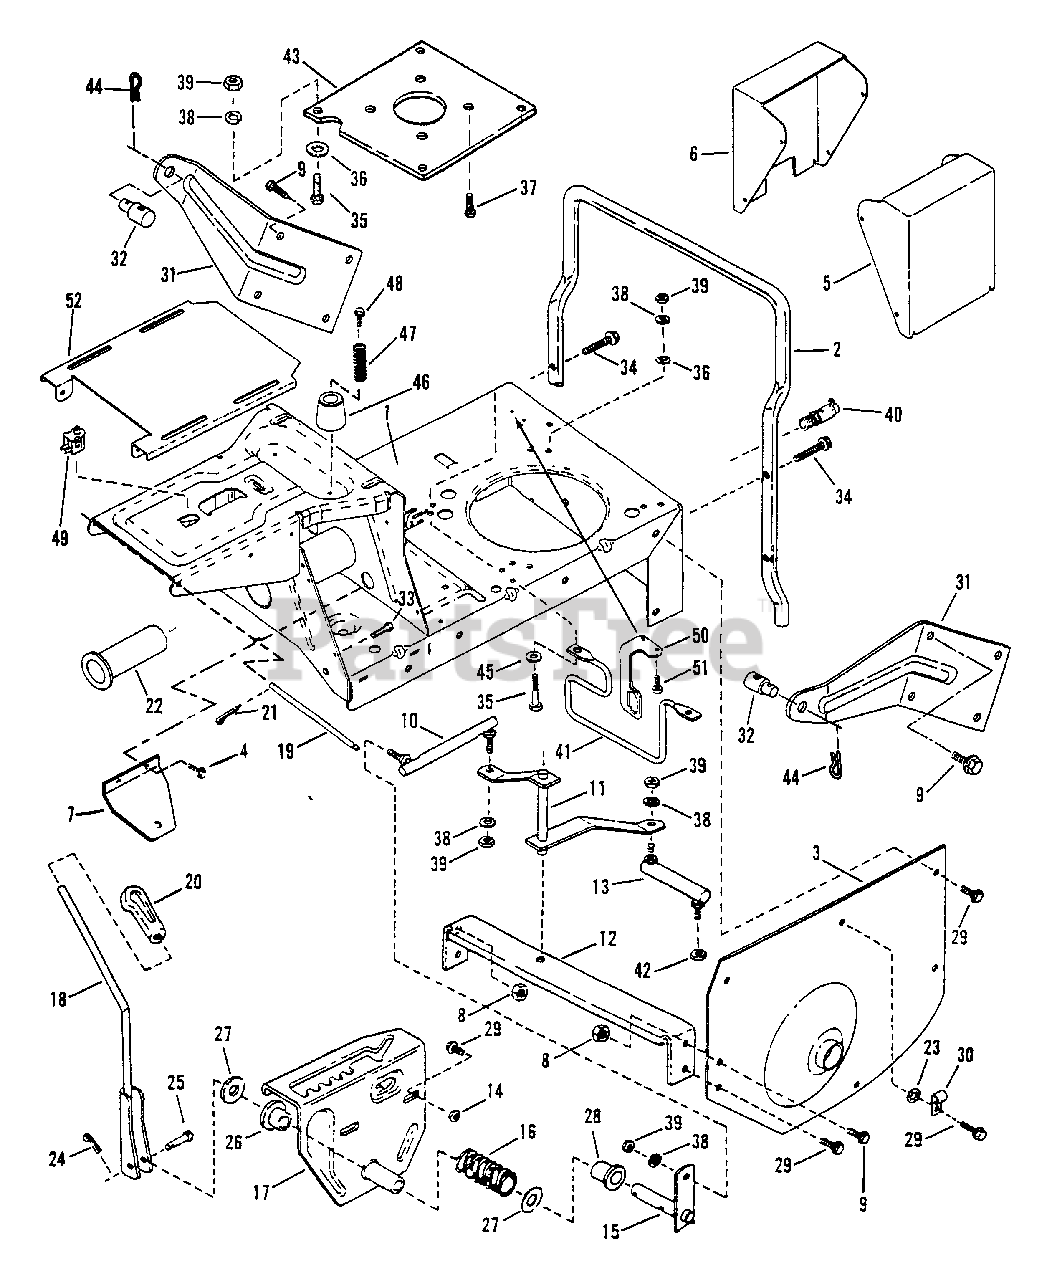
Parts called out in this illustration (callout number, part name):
2	BUMPER, Rear (42" Models)
3	FENDER, Left Hand
4	SCREW, 1/4-20 x 1/2" Self-Tapping
5	COVER, Battery (42" Models)
6	COVER, Switch
7	PLATE, Choke (42" Models)
8	NUT, 5/16-18 Hex Flange Lock
9	SCREW, 5/16-18 x 3/4" Self-Tapping
10	LINK, Shift (Long)
11	ARM, Shift
12	BRACE, Cross
13	LINK, Shift (Short)
14	NUT, 5/16-18 Hex(2)
15	ARM, Shift Handle
16	SPRING, Shift Handle
17	DETENT, Shift
18	HANDLE, Shift
19	HINGE, Pin
20	KNOB, Shift Handle
21	PIN, 1/16 x 3/4" Cotter
22	BUSHING, Pilot
23	WASHER, 5/16 Internal Tooth Lock
24	PIN, 3/32 x 3/4" Cotter
25	PIN, 1/4 x 1-3/4" Tapered Clevis
26	BUSHING, Nylon
27	WASHER, Thrust
28	BUSHING, Nylon
29	SCREW, 5/16-18 x 5/8" Self-Tapping
30	CLIP, Wire
31	WING, Rear Deck
32	SWIVEL
33	FASTENER, Ratchet
34	SCREW, 5/16-18 x 1-1/2" Self-Tapping
35	SCREW, 5/16-24 x 1" Hex Head Cap
36	RETAINER, 5/16 Bolt
37	SCREW, 3/8-16 x 1" Self-Tapping
38	WASHER, 5/16" Split Lock
39	NUT, 5/16-24 Hex
40	ASSEMBLY, Oil Drain
41	GUIDE, Belt (42" Models)
42	NUT, 5/16-24 Hex Flange Lock
43	PLATE, Engine
44	PIN, 3/32 x 1-1/2" Hair
45	WASHER 11/32 x 11/16 x 1/16"
46	CUSHION, Seat Support
47	SPRING, Seat (Operator's Presence Control)
48	SCREW, Self Tapping 1/4-20 x 5/8" TORX
49	SWITCH, Seat
50	BRACKET, Switch
51	SCREW, 1/4-15X3/4, Self-Tapping, BZ
52	PLATE, Seat
